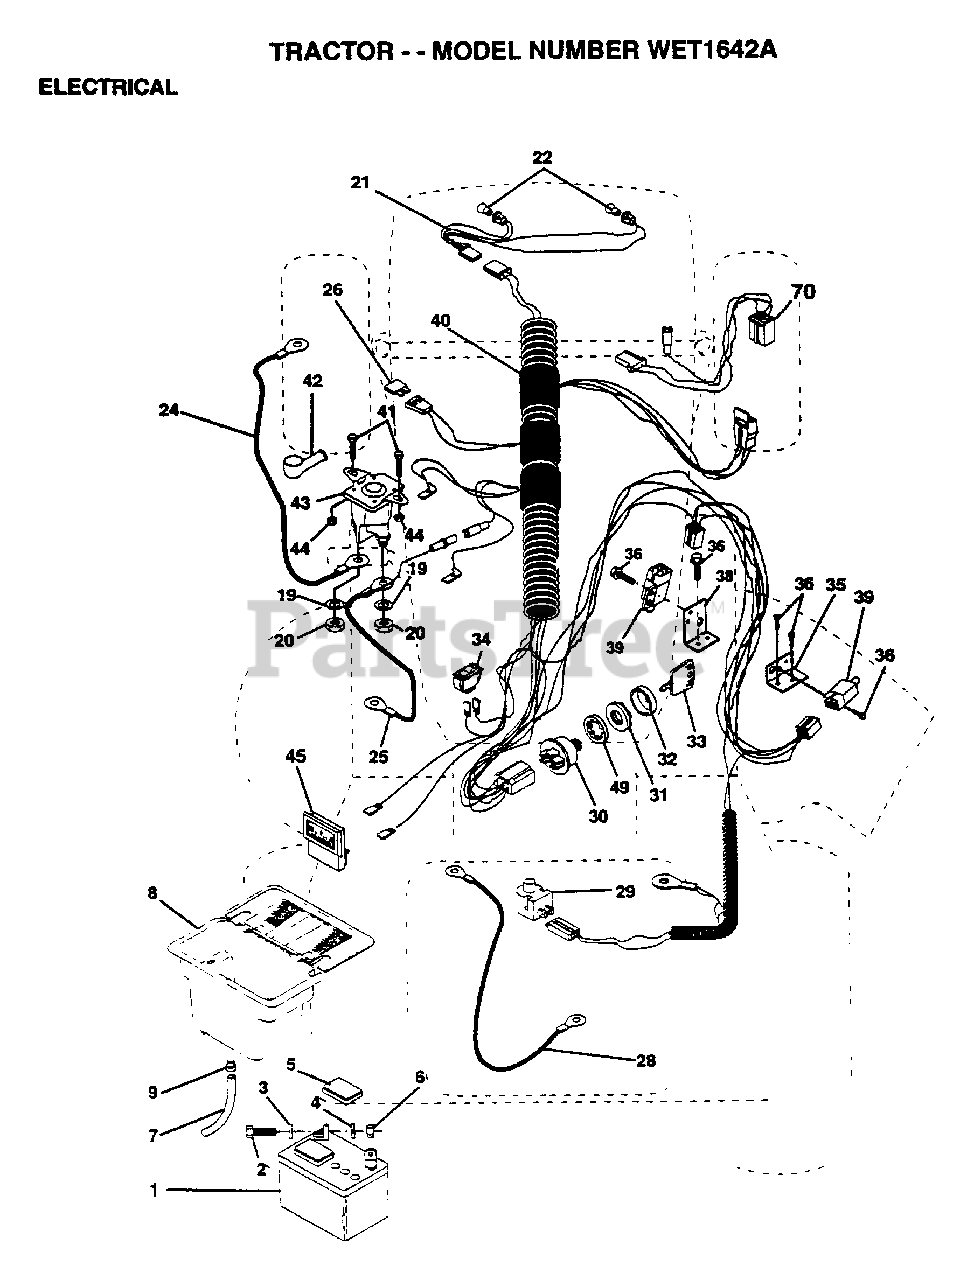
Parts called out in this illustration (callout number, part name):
2	BOLT LT
3	WASHER
4	LOCKWASHER
5	"CAP,BATTERY "
7	TUBE T
9	HOSE CLAMP T
20	NUT
21	"HARNESS,LIGHT SOC"
22	HEADLAMP BULB
24	"CABLE T, BATTERY"
25	CABLE.BTRY.6GA.RD
26	FUSE HYT
28	CABLE T
29	SWITCH SEAT
32	COVER KEY SWITCH
33	KEY MLD GEN DELTA
34	SWITCH LT
35	BRACKET LT
36	SCREW
38	BRACKET SWITCH IN
39	SWITCH INTERLOCKT
40	HARNESS.IGN.DASH.
41	BOLT.HX.1/4-20
44	NUT
49	LOCKWASHER
70	HARNESS ENG DUAL
